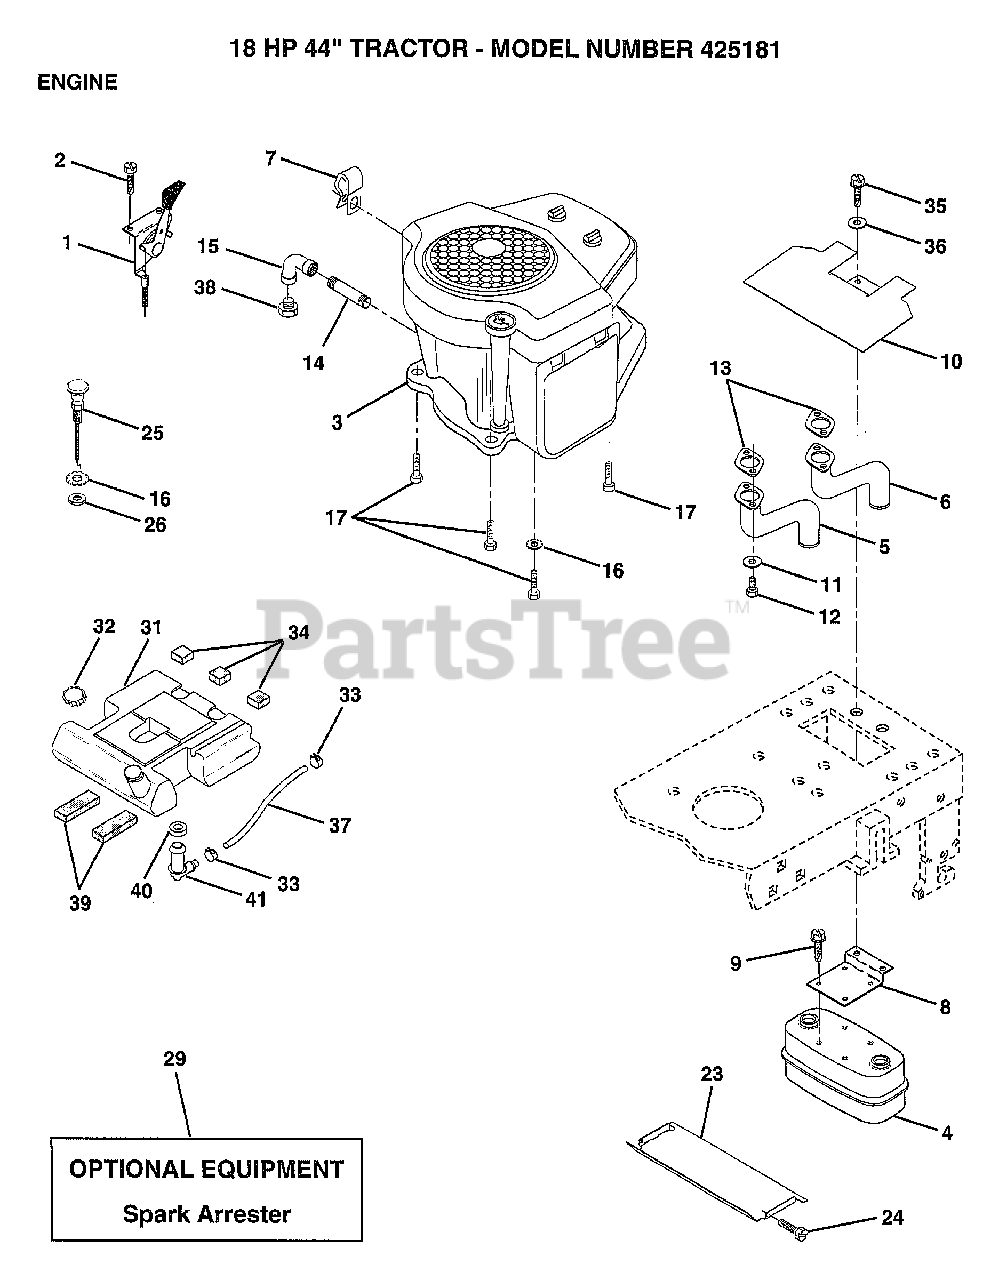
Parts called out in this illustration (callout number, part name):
1	CONTROL.THROTTL
2	SCREW LT
5	"TUBE,MANIFOLD LH"
6	"TUBE,MANIFOLD RH"
7	CLAMP.TUBE.DBL.EN
8	BRACKET MUFFLER
9	SCREW ST
10	SHIELD HEAT LT
11	LOCKWASHER
12	SCREW
14	PIPE NIPPLE LT
15	ELBOW
16	LOCKWASHER
17	SCREW LT
23	HEAT SHIELD
24	SCREW
32	CAP ASM FUEL
33	HOSE CLAMP
34	PAD-SPACER LT
35	SCREW
36	WASHER
37	FUEL LINE T
39	PAD IDLER TI
40	BUSHING OUTLET T
41	STEM.TANK.FUEL
